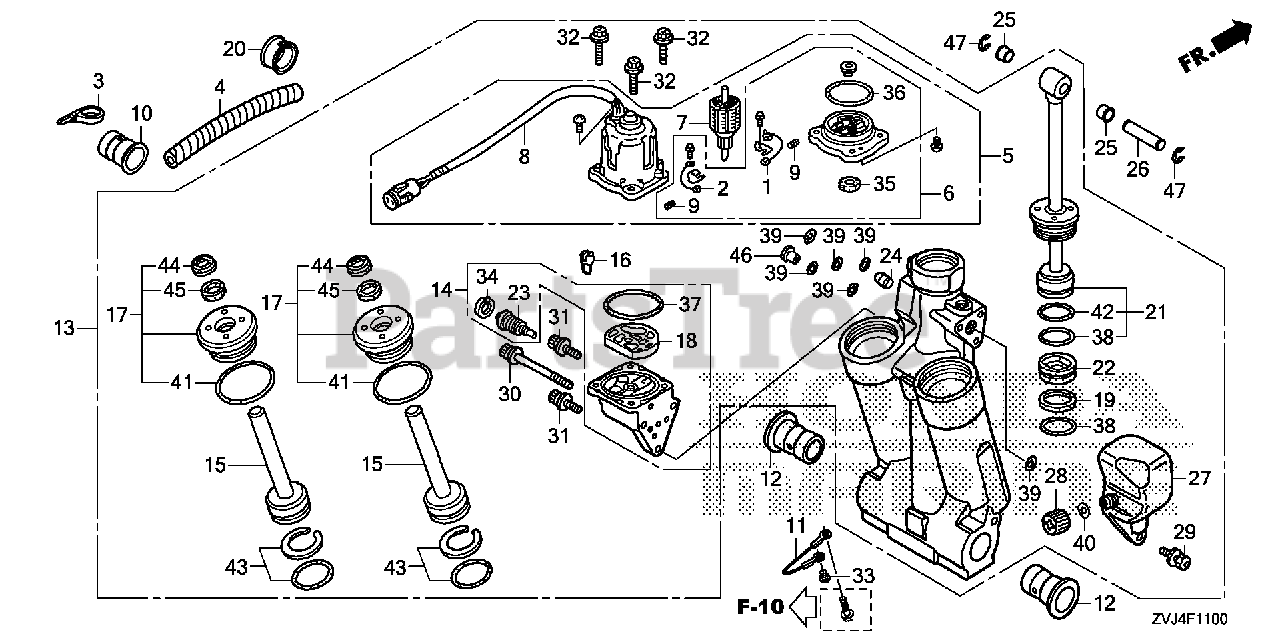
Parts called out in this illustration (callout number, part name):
1	BREAKER ASSY.
2	BRUSH ASSY.
3	BAND (BLACK 3.5X140)
4	TUBE, SPIRAL (12X14.6)
5	MOTOR ASSY., POWER TILT
6	BRACKET ASSY.
8	YOKE ASSY.
9	SPRING, MOTOR
10	GROMMET, CASE (LOWER) (C)
11	WIRE, LEAD (1.5X116MM)
12	BUSH, SWIVEL CASE
13	TRIM-TILT ASSY., POWER
14	PUMP ASSY.
15	ROD, PISTON (B)
16	JOINT, DRIVE
17	GUIDE, ROD
18	FILTER (B)
19	RING, BACK-UP
20	BUSH, MOTOR CODE
21	ROD, PISTON
22	PISTON, FREE
23	VALVE, MANUAL
24	VALVE, RESERVOIR
25	BUSH, CYLINDER (LOWER)
26	PIN, CYLINDER (UPPER)
27	TANK, OIL
28	CAP, OIL TANK
29	BOLT, RECESSED
30	BOLT A, SOCKET
31	BOLT B, SOCKET
32	BOLT, HEX.
33	SCREW, PAN (6X8)
34	CIRCLIP (INNER)
36	O-RING (2.0X70.5)
37	O-RING (1.8X69.6)
38	O-RING (3.5X38.7)
39	O-RING (1.68X7.25)
40	O-RING (1.9X11)
41	O-RING (3.5X35.7)
42	O-RING (3.5X41.7)
43	O-RING SET (3.5X31.7)
44	SEAL, WATER
46	COLLAR, ORIFICE
47	E-RING (15MM)
